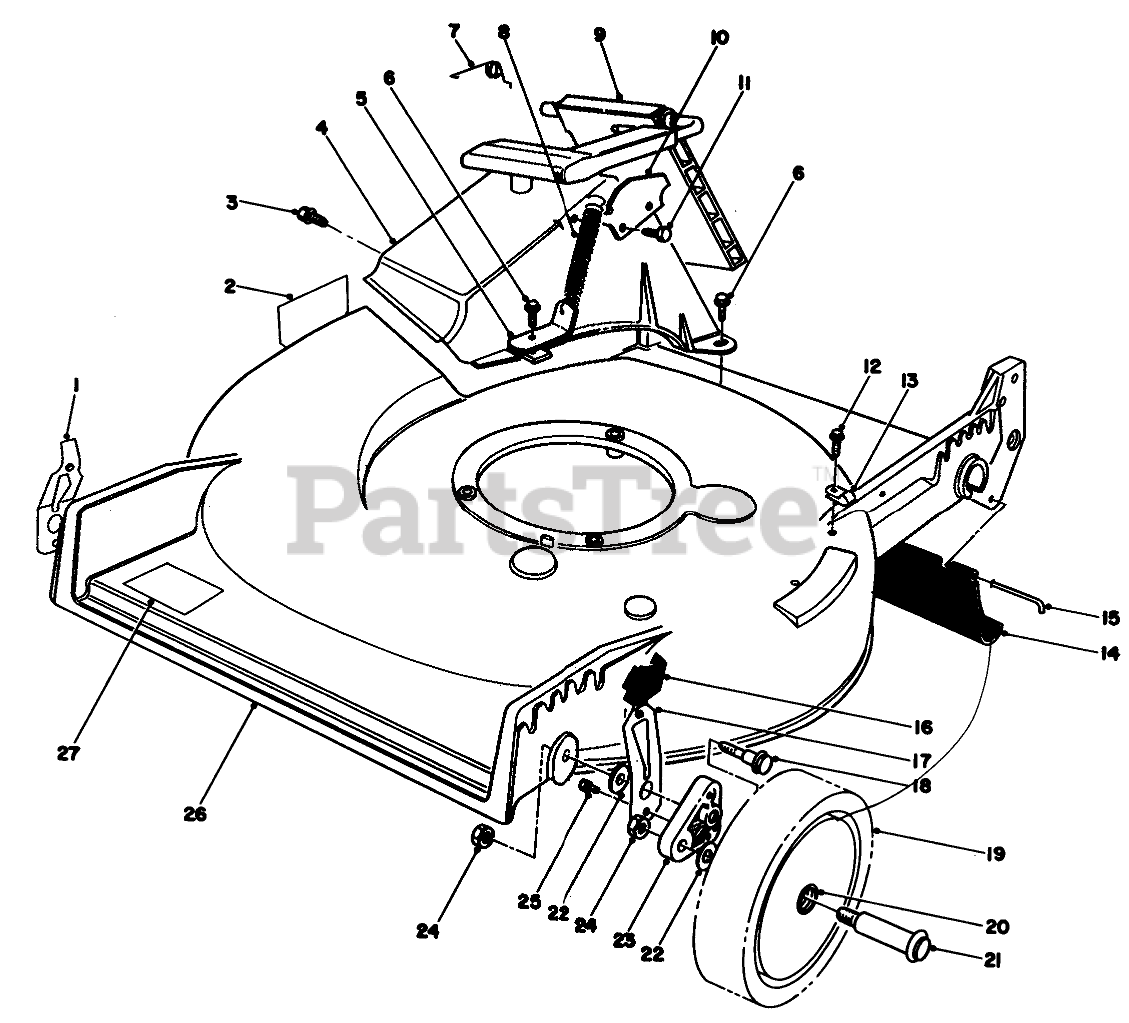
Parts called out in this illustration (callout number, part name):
1	RH SPRING ARM ASSEMBLY
2	DECAL-DANGER
3	SCREW AND WASHER ASM
4	DISCHARGE TUNNEL
5	Bracket-Spring
6	SCREW-HWH
7	RETAINER-DOOR
8	SPRING-DOOR
9	DOOR ASSEMBLY
10	DOOR LATCH PLATE
11	SCREW-PLASTITE
12	SCREW-HWHTF
13	CLAMP-R
14	SHIELD-TRAILING
15	ROD-SHIELD
16	KNOB-ARM
17	LH SPRING ARM ASSEMBLY
18	SCREW-SHOULDER
19	Wheel & Tire Assembly (Incl. Ref. #20)
20	BUSHING
21	WHEEL BOLT
22	WASHER
23	ARM-PIVOT, FRONT
24	Nut
25	SCREW-HWH
26	Housing Assembly (Incl. Ref. #2 & 6)
27	DECAL
